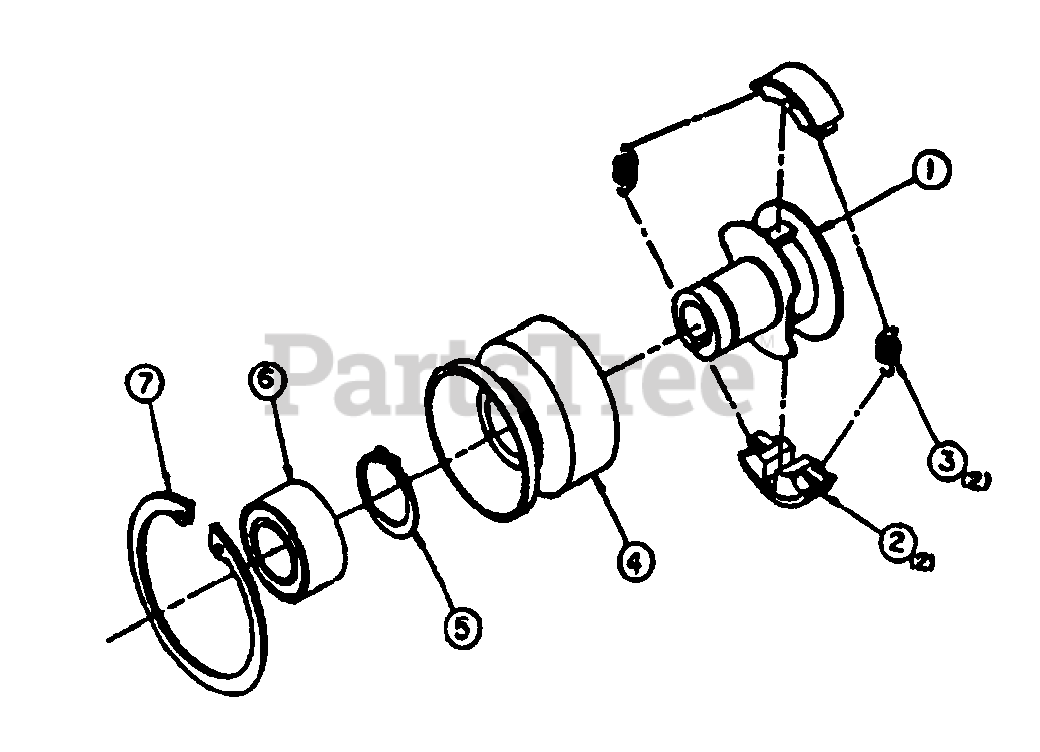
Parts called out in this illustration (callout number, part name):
1	Hub Assembly
4	Drum Assembly
5	Retaining Ring
6	Bearing
7	Retaining Ring
